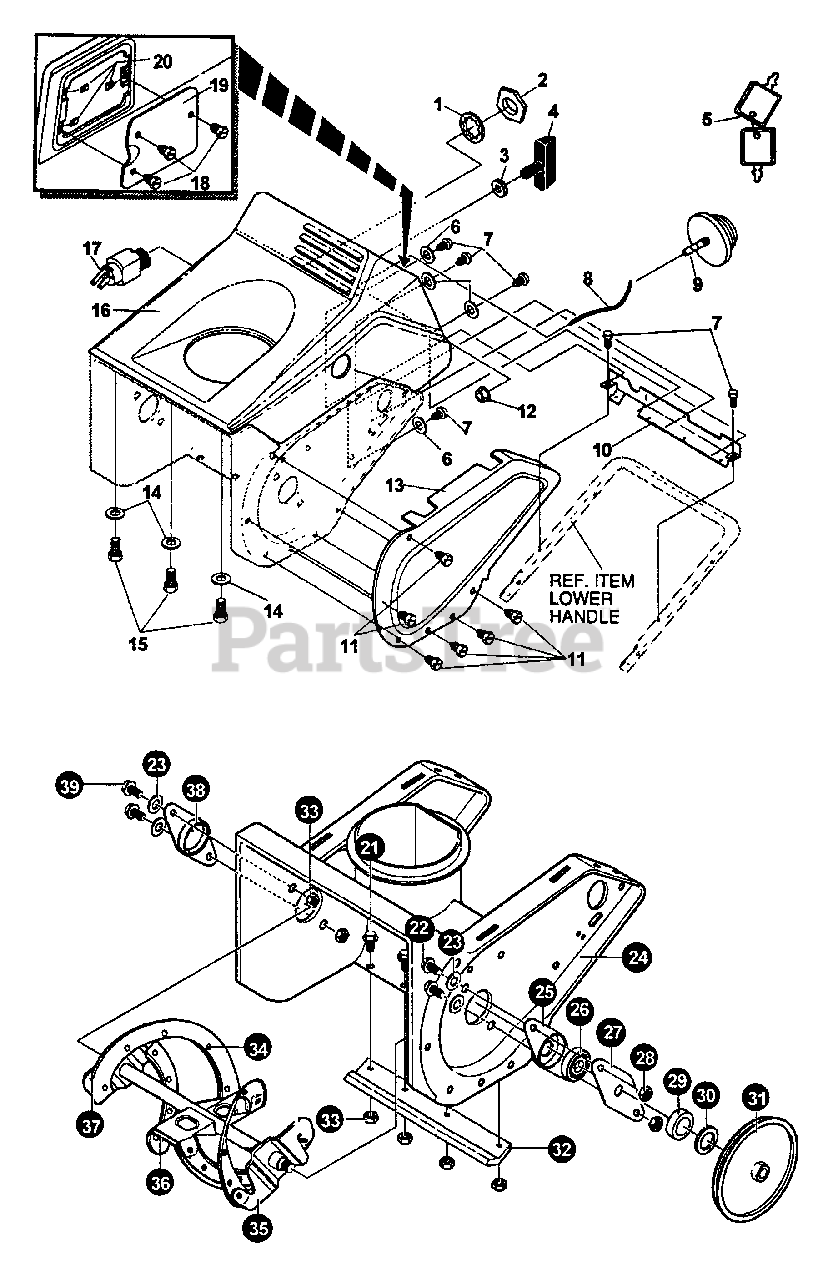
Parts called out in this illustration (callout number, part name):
1	WASHER
2	NUT
3	GROMMET & WASHER, ROPE GUIDE
4	KNOB, TEE
5	KEYS & RING ASSY
6	WASHER
7	SCREW - 10-24 X .63"
8	HOSE, PRIM 5.75 LONG
9	PRIMER, ENGINE 2CY
10	BRACKET, SHROUD MNTG
11	SCREW - 10-24 X 3/8"
12	NUT - 1/4-20 -- KEPS
13	COVER, BELT
14	WASHER
15	SCREW - 10-14 X .63"
16	COVER - TOP
17	SWITCH, IGNITION
18	SCREW - 10-16 X .75"
19	DOOR, ACCESS
20	NUT
21	SCREW - 1/4-20 X 5/8"
22	SCREW - 1/4-20
23	WASHER
24	AUGER INTAKE ASSY - 21"
25	RETAINER, BEARING
26	BEARING, BALL - 6203
27	RETAINER, BEARING
28	NUT - 1/4-20
29	SPACER, SLEEVE .640 X .88 X .15
30	WASHER - .640 X 1.25 X .06
31	PULLEY, POLYV 6" OD 10 RIB
32	BLADE, SCRAPER
33	LOCKNUT - 1/4-20
34	RIVET - .250 X .5"
35	AUGER ASSY - 21"
36	AUGER, CENTER BLADE STRIP
37	AUGER, BLADE STRIP
38	BEARING, FLANGE
39	SCREW - 1/4-20 X 7/8"
